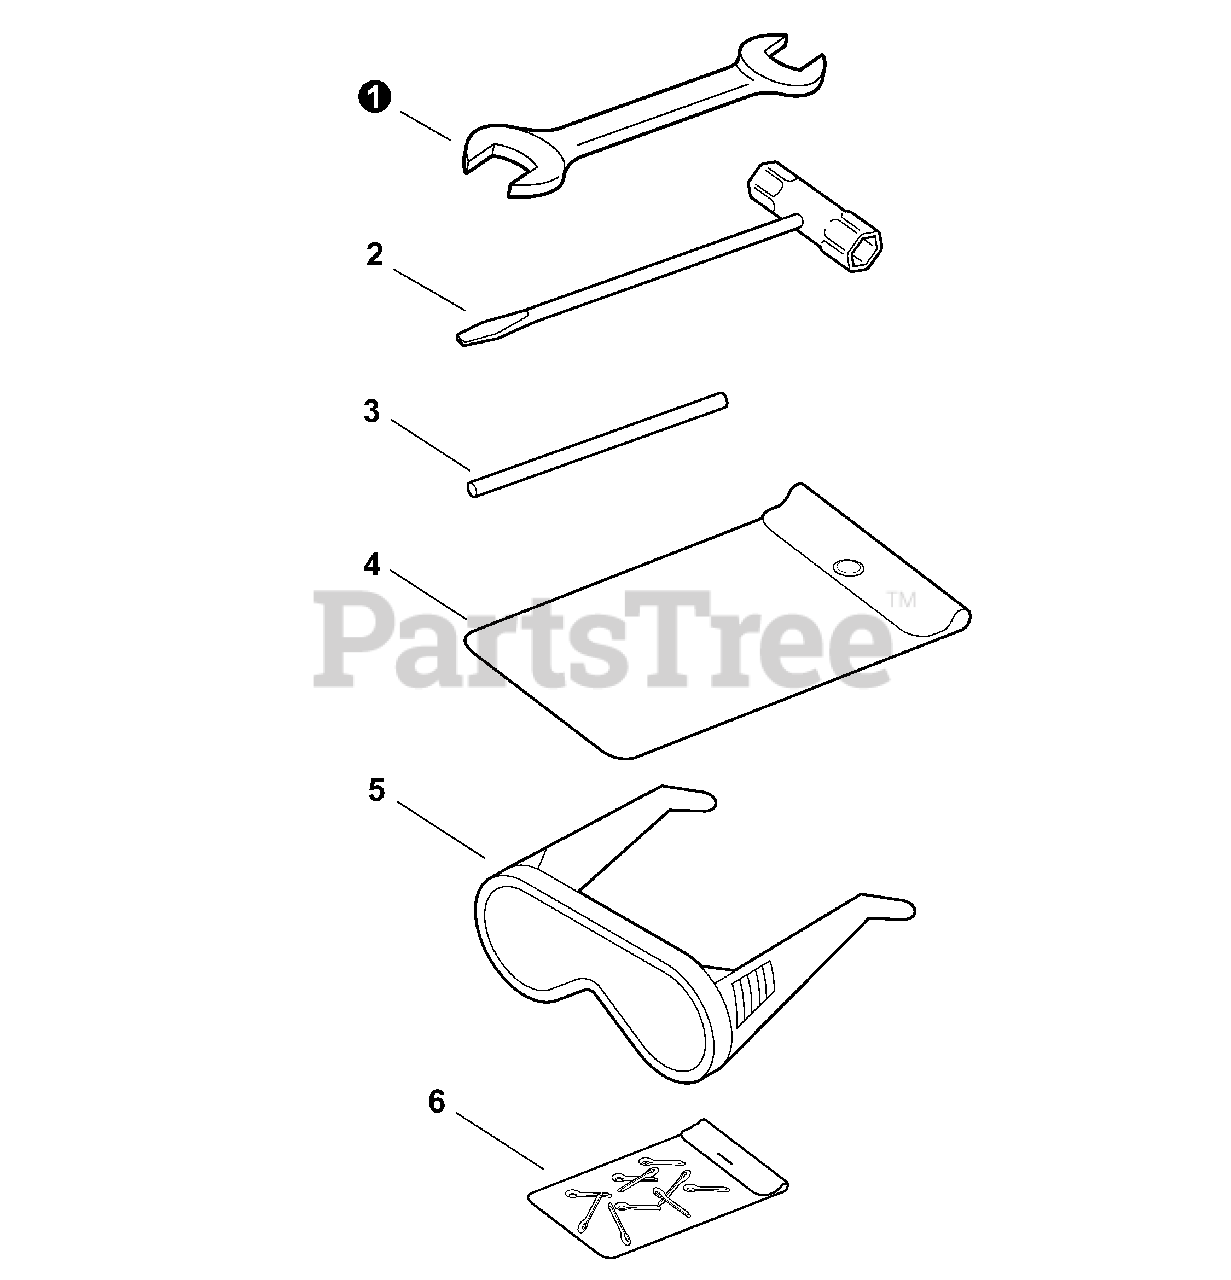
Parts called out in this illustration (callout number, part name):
1	SPANNER 8×10
2	T-WRENCH 17x-19 L200
3	TOOL, LOCKING 5×120 MM
4	BAG, TOOL
5	GLASSES, SAFETY
6	PIN, COTTER 2×22
